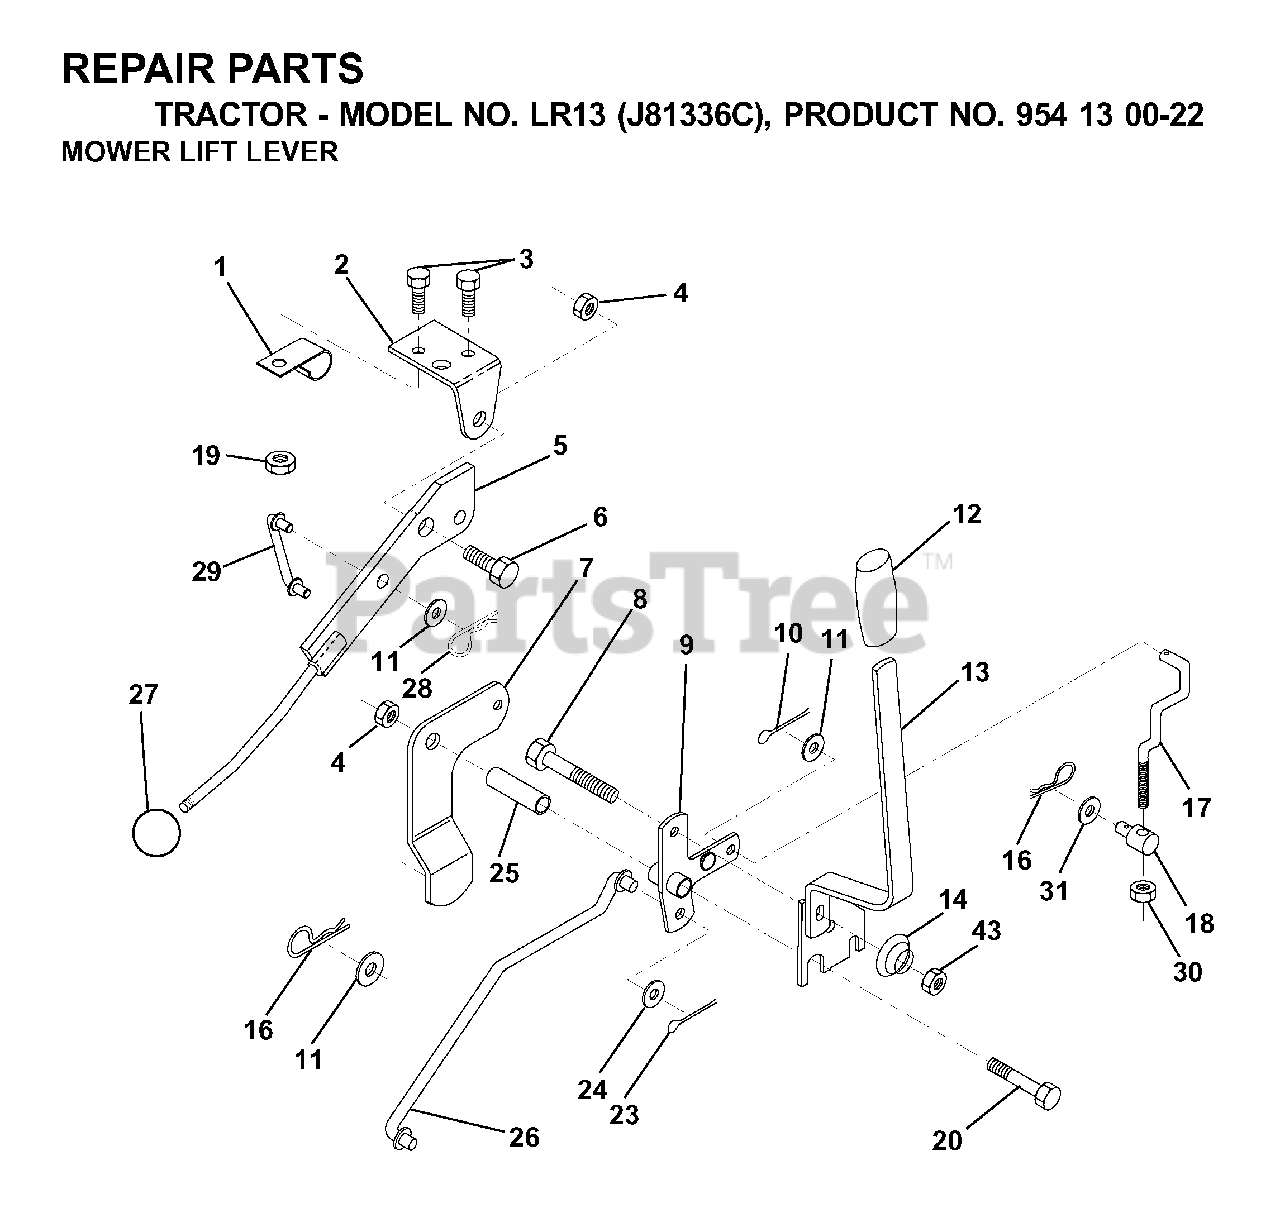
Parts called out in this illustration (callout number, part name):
1	CLIP,INSULATOR
2	BRKT CLUTCH
4	LOCKNUT
5	CLUTCH LEVER
6	BOLT, SHOULDER LT
7	ASSEMBLY MOWER CLUTCH ARM
9	BELLCRANK,LIFT
10	COTTER PIN
12	GRIP HANDLE
13	LIFT HANDLE ASSY
14	SPRING COMPRESSIO
16	SPRING TI
17	LINK LIFT FRT
19	NUT.CROWNLOCK.1/4
23	PIN COTTER
24	WASHER GT
25	TUBE SPACER
27	KNOB
28	RETAINER M
29	LINK MOWER CLUTCH
30	NUT
43	NUT LOCK FLG 3/8-16 UNC
